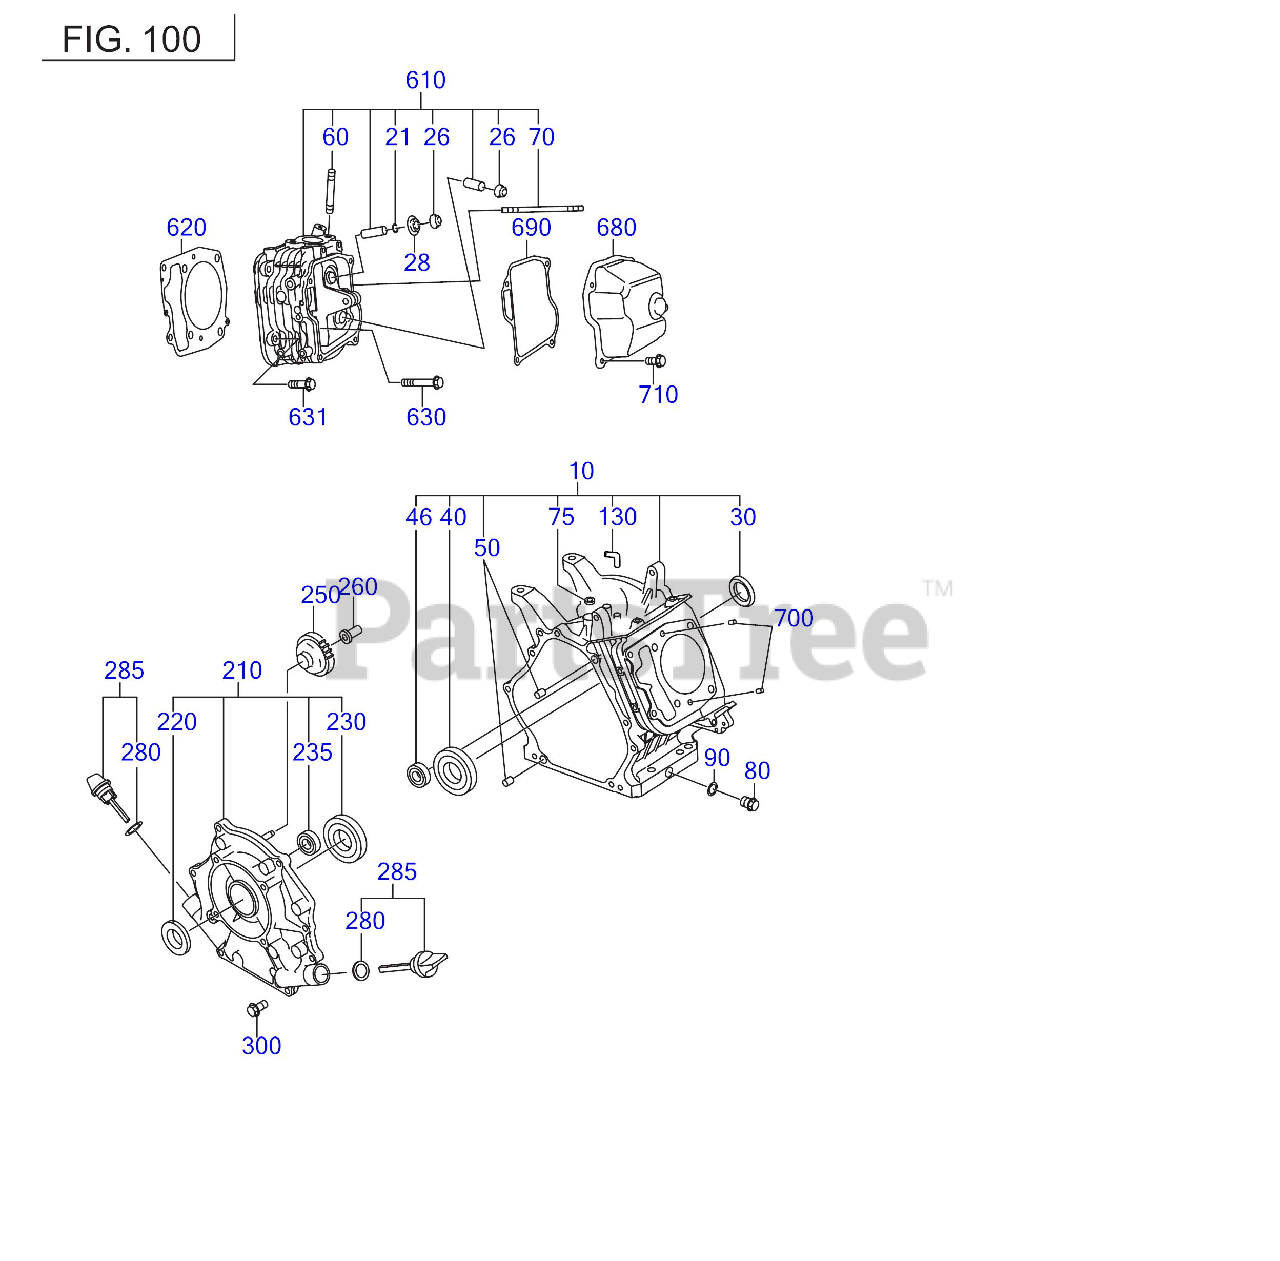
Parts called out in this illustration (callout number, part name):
10	CRANKCASE CP
26	SEAL-EXH VALVE
28	RETAINER PLATE
80	OIL DRAIN PLUG
210	MAINBEARING COVER CP
250	GOVERNOR GEAR CP
260	GOVERNOR SLEEVE
610	CYLINDER HEAD AY
680	ROCKER COVER CP
690	GASKET(ROCKER COVER)
